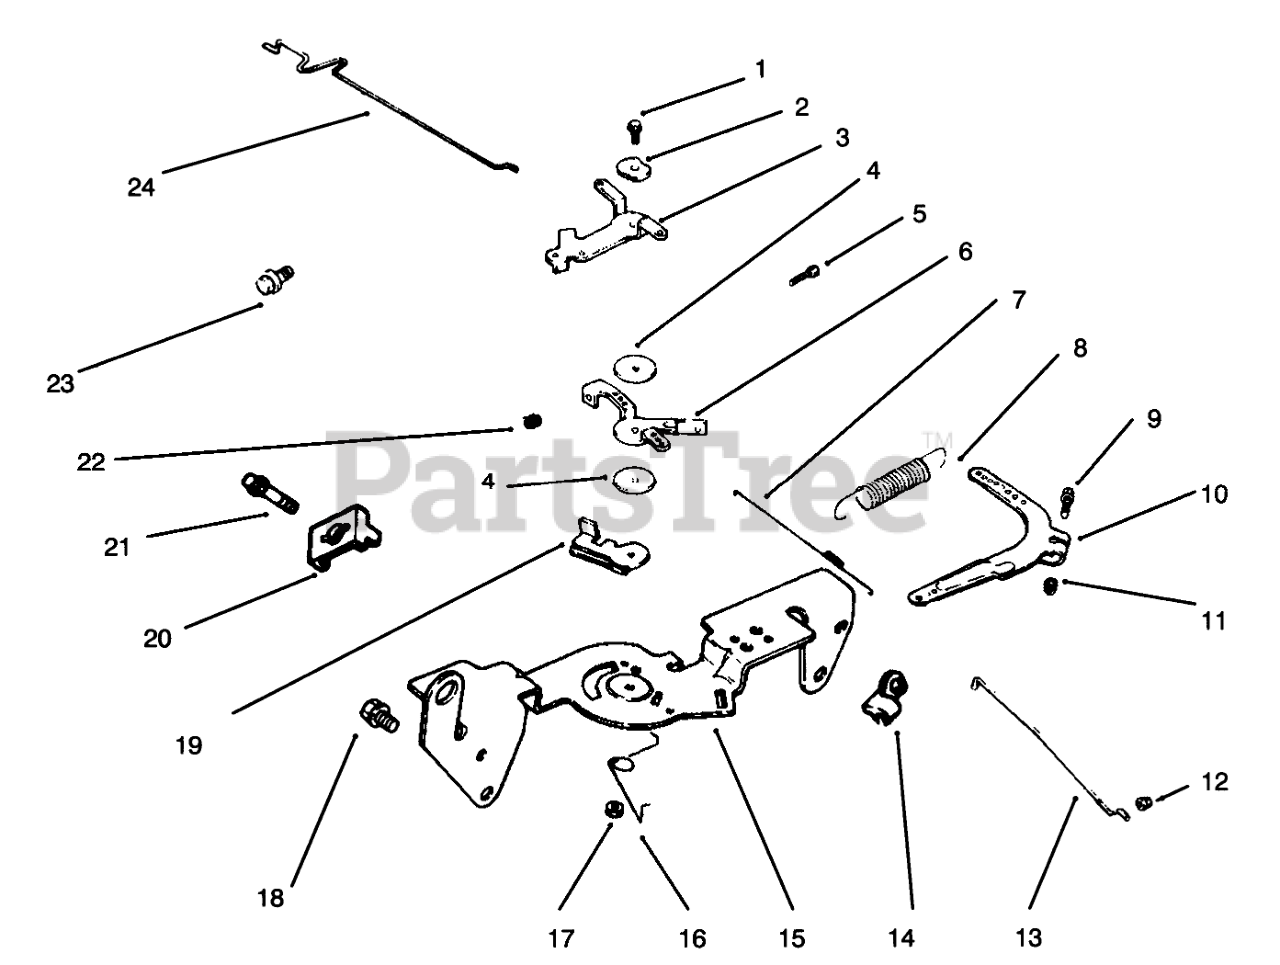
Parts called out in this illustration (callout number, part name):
1	Screw
2	Washer-Wave
3	Lever-Choke
6	Spring-Linkage
7	Lever-Throttle Control
8	Spring-Governor
9	Screw
10	Lever-Governor
12	Bushing
13	Linkage-Throttle
14	Bushing-Linkage
15	Bracket-Control
16	Nut
17	Spring-Choke Return
19	Lever-Throttle Actuator
22	Nut
23	Screw
24	Linkage-Choke
